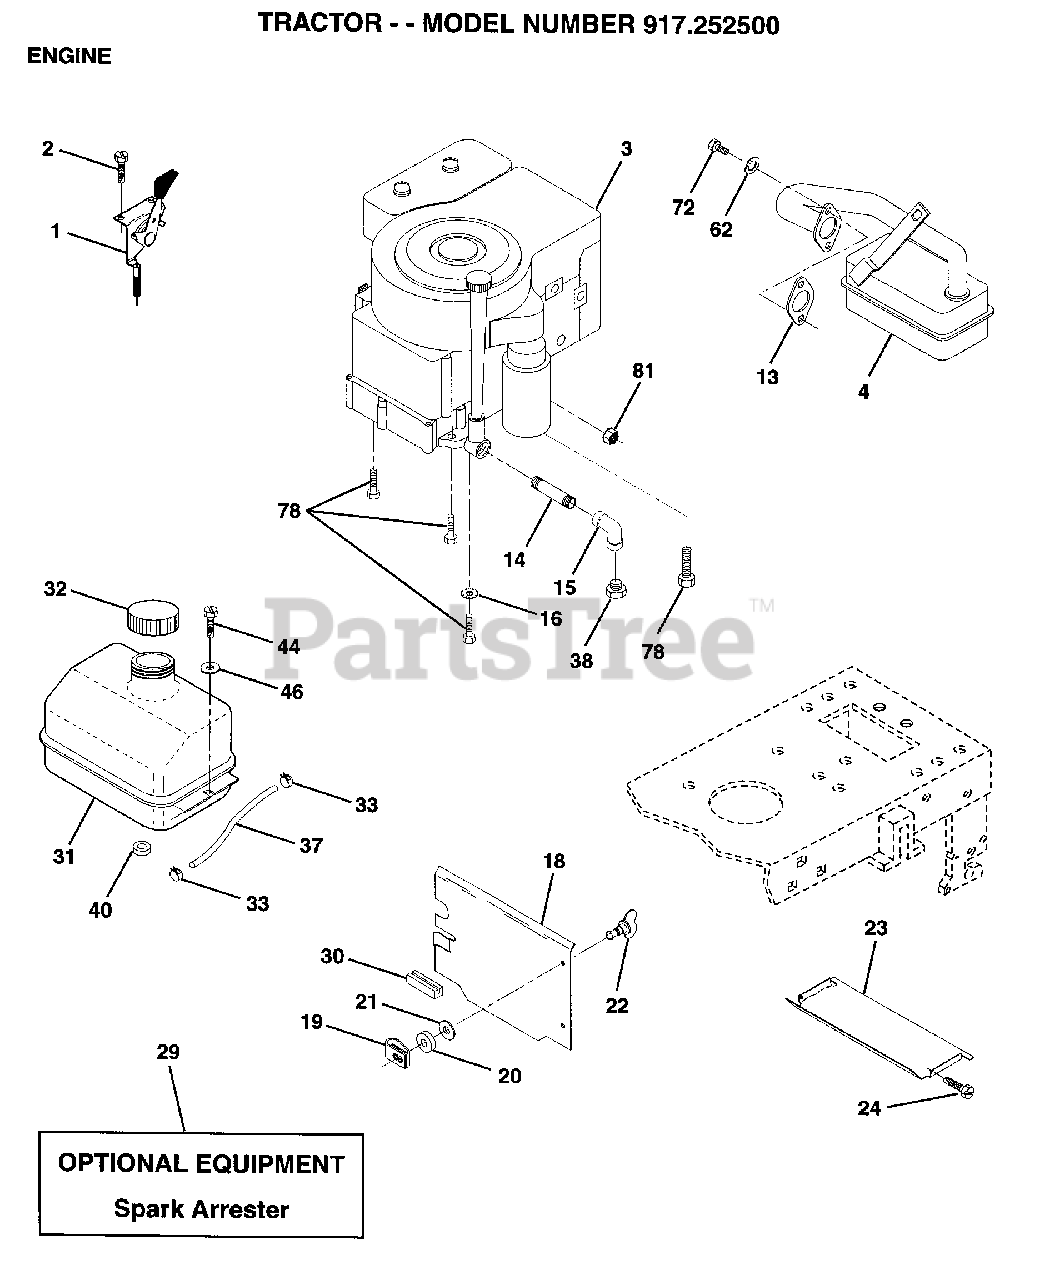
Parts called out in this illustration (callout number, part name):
2	SCREW LT
3	ENGINE SAM B&S DMD 13EEC ICGLD
4	MUFFLER
14	PIPE NIPPLE
15	ELBOW
16	LOCKWASHER
18	SHIELD HEAT
19	RECEPTACLE LT
20	RETAINER LT
21	WASHER
22	STUD.1/4.TURN
23	HEAT SHIELD
24	SCREW
31	TANK.FUEL.LT.
33	HOSE CLAMP
37	LINE FUEL
44	SCREW HEX CRT
46	WASHER
62	LOCKWASHER
72	SCREW
78	SCREW
81	NUT
